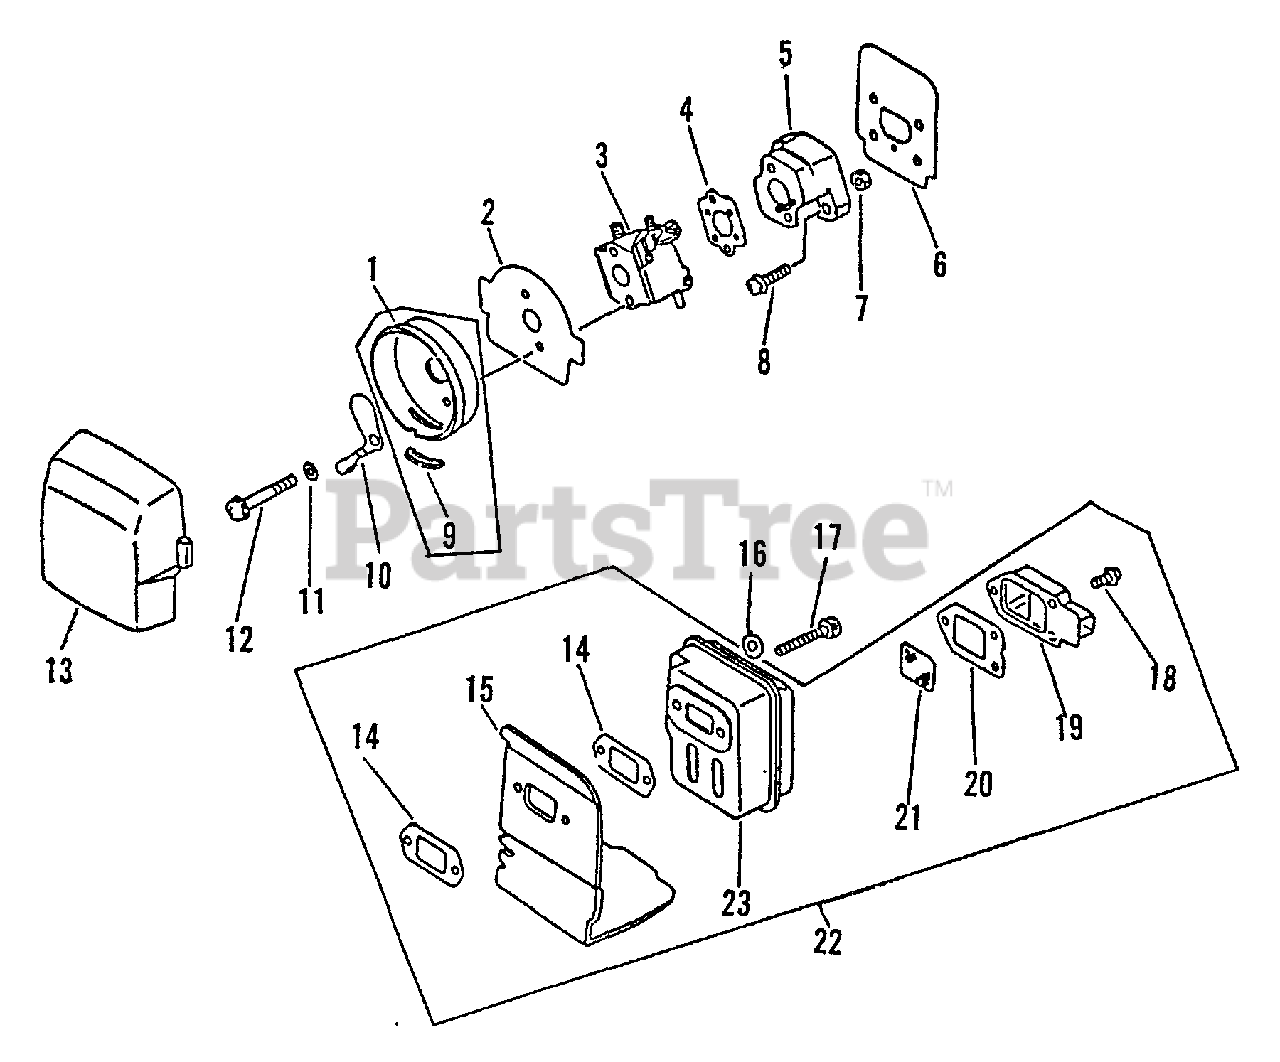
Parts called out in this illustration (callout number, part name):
1	Case, Air Cleaner
2	Fixture, Air Cleaner
3	Carburator, C1U-K9
4	Gasket, Intake
5	Insulator
6	Gasket, Intake
8	Screw 5x20
9	Grommet, Choke
10	Shutter, Choke
11	Washer 5
12	Screw 5x57
13	Filter, Air
14	Gasket, Muffler
15	Cover, Muffler
16	Washer 5
17	Bolt, H.S. 5x35
18	Screw 4x10
19	Holder, Screen
20	Gasket, Muffler Lid
21	Screen, Muffler
22	Muffler Asy
